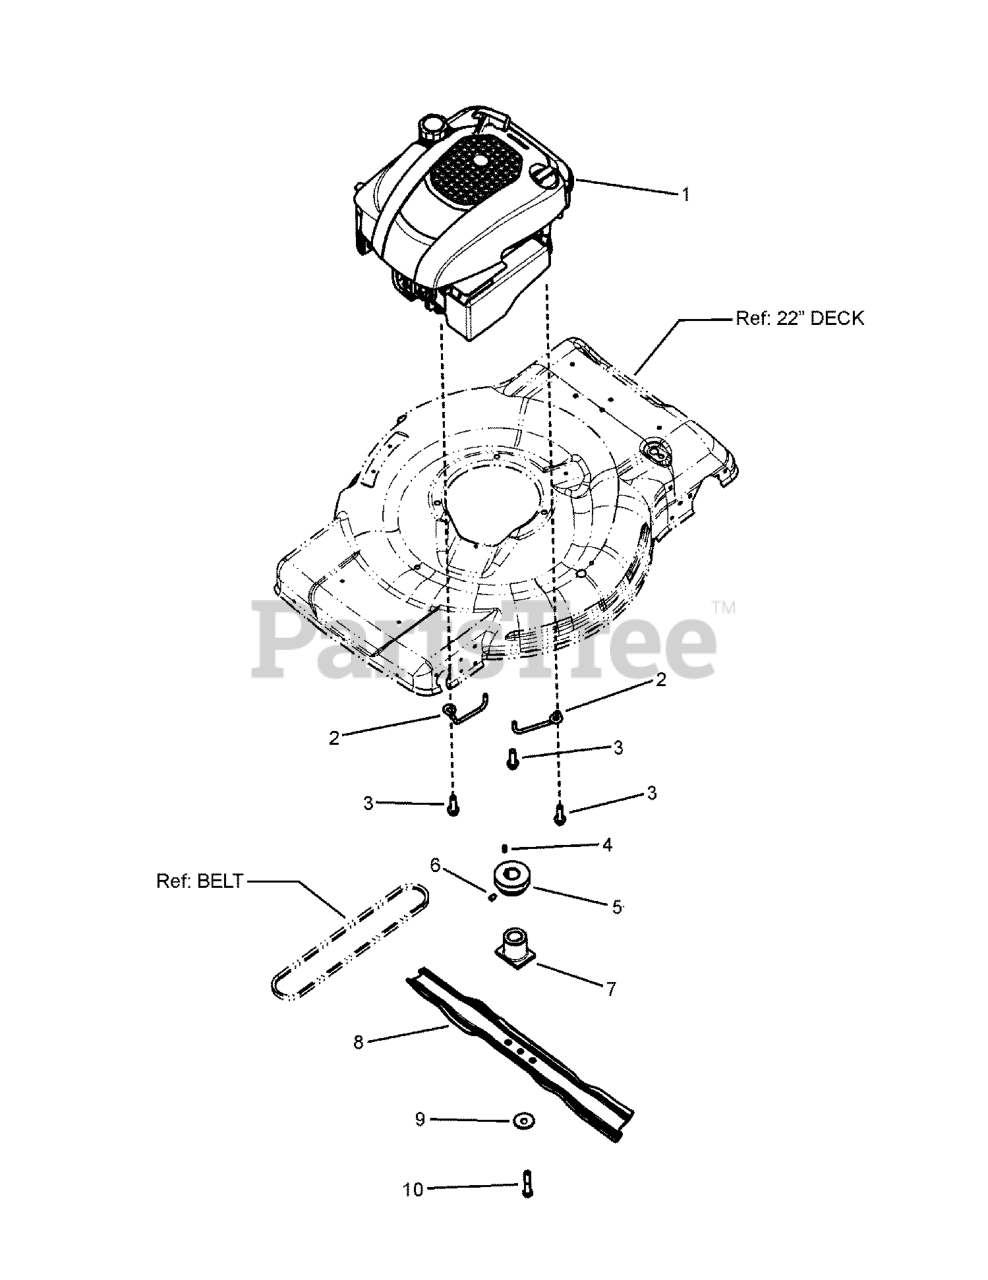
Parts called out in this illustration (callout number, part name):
1	ENGINE, W-14, 875 SERIES W/ ES AND OIL FILTER, DEERE
2	BELT GUIDE, ENGINE, FWD
3	SCREW, HWST, 3/8-16 X 1.25
4	KEY, #HP-506 HI-PRO
5	PULLEY, ENGINE
6	SET SCREW, HRSS, 5/16-18X1/2
7	HUB, BLADE, 21" WBM, RD, 2 POSITION
8	BLADE, WAVE, STEEL DECK
9	WASHER, CONE
10	SCREW, HHCS, 3/8-24X2 GR5
